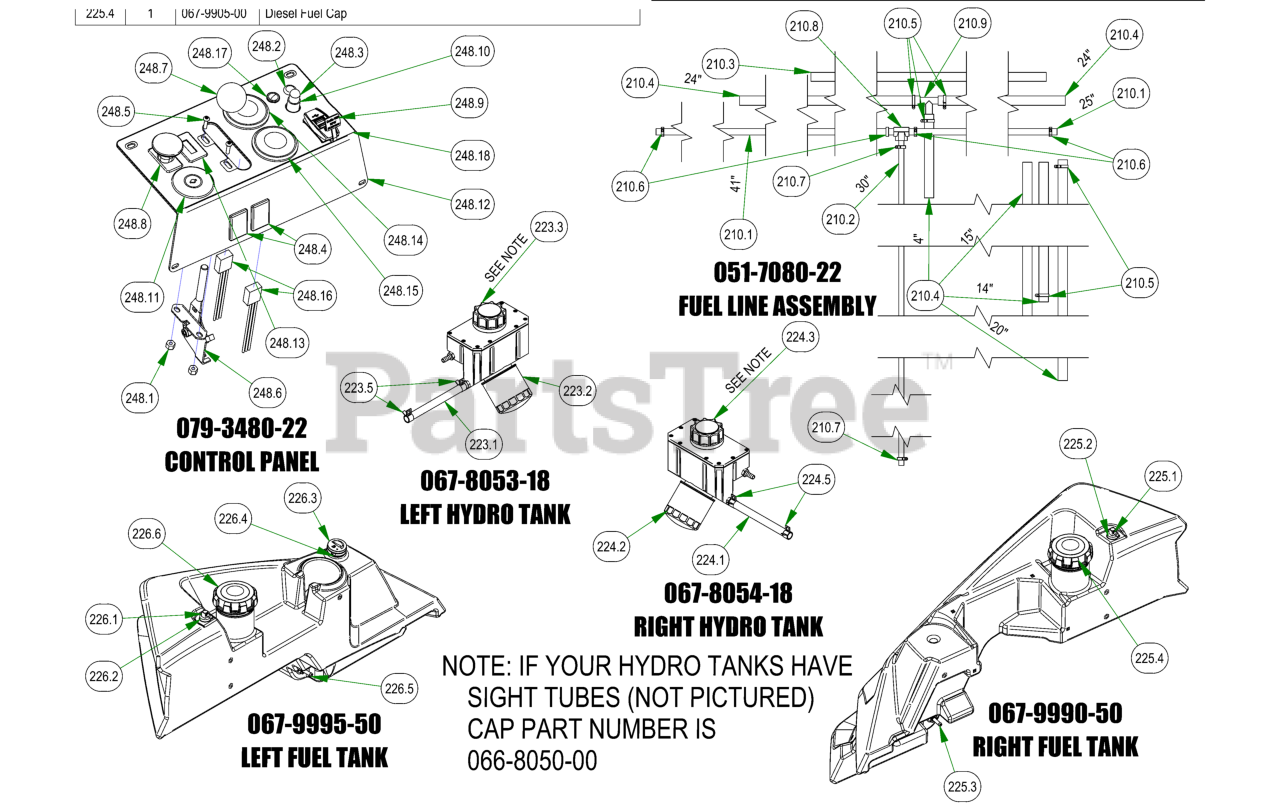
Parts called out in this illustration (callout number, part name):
210	2022 Renegade Diesel Fuel Line Assembly
210.1	1/4" Fuel Line Hose
210.2	3/16 Fuel Line
210.3	5/16 Clear Hose
210.4	5/16" fuel line hose
210.5	5/16 Fuel Line Clamp
210.6	1/4 Fuel Hose Clamp
210.7	3/16 Vinyl Clamp
210.8	Brass fuel line T
210.9	5/16 x 5/16 x 1/4 Fuel Line T
223	LH Rogue Hydro Tank Assy
223.1	1/2 Clear Braded Hose Priced/FootSE
223.2	N Hydraulic FilterOTE
223.3	Hydraulic Tank Cap W/Dipstick
223.4	2019 Left Outlaw Gen2 Hydro Tank Suspension Only
223.5	1/2 Hose Clamp
224	RH Rogue Hydro Tank Assy
224.1	1/2 Clear Braded Hose Priced/Foot
224.2	Hydraulic Filter
224.3	Hydraulic Tank Cap W/Dipstick
224.4	2019 Right Outlaw Gen2 Hydro Tank Suspension Only
224.5	1/2 Hose Clamp 41"
225	2019 Right Renagade Fuel Tank (diesel)
225.1	90 Degree Elbow Fitting
225.2	Nitrile Bushing
225.3	Fuel Pick-up
225.4	Diesel Fuel Cap30
226	2019 Left Renegade Fuel Tank (Diesel)
226.1	90 Degree Elbow Fitting
226.2	Nitrile Bushing
226.3	Fuel Gauge
226.4	Fuel Gauge Grommet
226.5	Fuel Pick-up
226.6	Diesel Fuel Cap
248	Renegade Control Panel Assembly
248.1	10-24 Nylon Insert Locknut
248.2	5/8 Round Insert
248.3	Start Switch Boot - Diesel
248.4	Light Plug
248.5	10-24 X 5/8 BS Button Head Bolt
248.6	Universal Throttle Head - 2012
248.7	Throttle Knob
248.8	PTO Switch
248.10	Momentary Start Switch
248.11	Ignition Switch
248.12	2019 Diesel Control Panel
248.13	Tachometer
248.14	2" Oil Pressure Gauge
248.15	2" Water Temperature Gauge
248.16	Diesel Gauge Adapter
248.18	2022 Renegade (Diesel) Control Panel Decal
